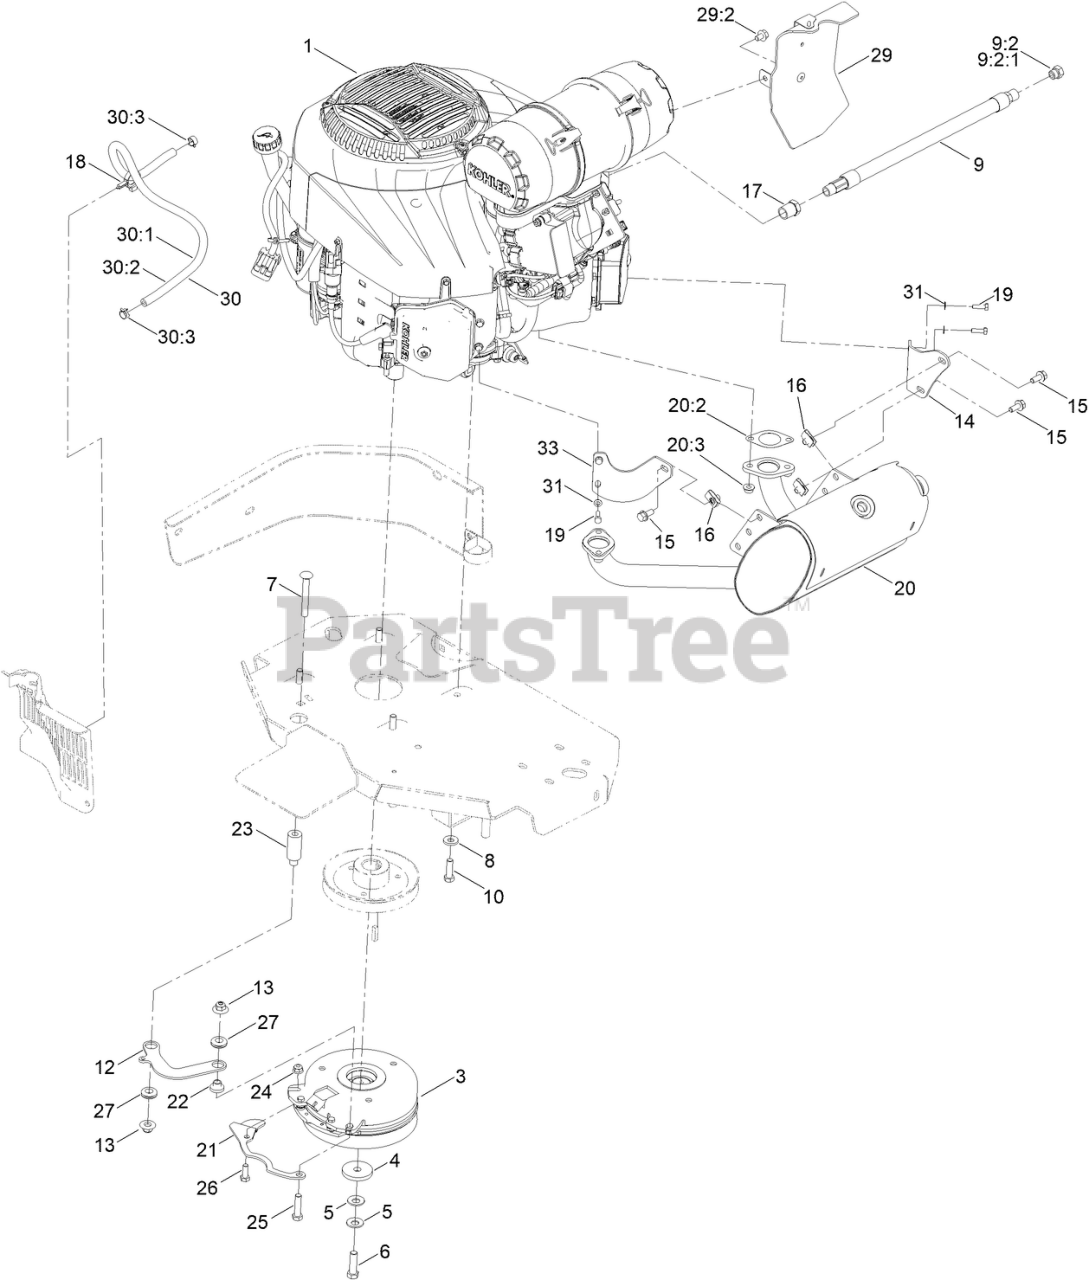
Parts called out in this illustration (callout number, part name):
3	CLUTCH KIT
4	WASHER-CLUTCH
5	WASHER-SPRING
6	SCREW-HH, W/LOCTITE
7	SCREW-CARR
8	WASHER-BELLEVILLE
9	OIL DRAIN HOSE ASM
9:2	PLUG-HH
9:2:1	O-RING
10	SCREW-HH
12	LINK-ANCHOR, CLUTCH
13	NUT-FLANGE, NI
14	BRACKET-MUFFLER
15	SCREW-HHF
16	NUT-U
17	BUSHING
18	CLAMP-HOSE
19	SCREW-HH
20	MUFFLER-940-980 KOH EFI
20	MUFFLER KIT
20:2	GASKET-EXHAUST
20:3	NUT-FLANGE, LOCK
21	BELT-GUIDE
22	SPACER
23	SPACER
24	NUT-HF, NI
25	SCREW-HH
26	SCREW-HH
27	GROMMET-RUBBER
29	BAFFLE ASM
29	BAFFLE KIT
29:2	SCREW-HWH
29:2	SCREW-HHF
30	FUEL LINE ASM
30:1	HOSE-FUEL
30:2	SLEEVE, THERMAL
30:3	CLAMP-HOSE
31	WASHER-SPRING
33	BRACKET-MUFFLER, FRONT
